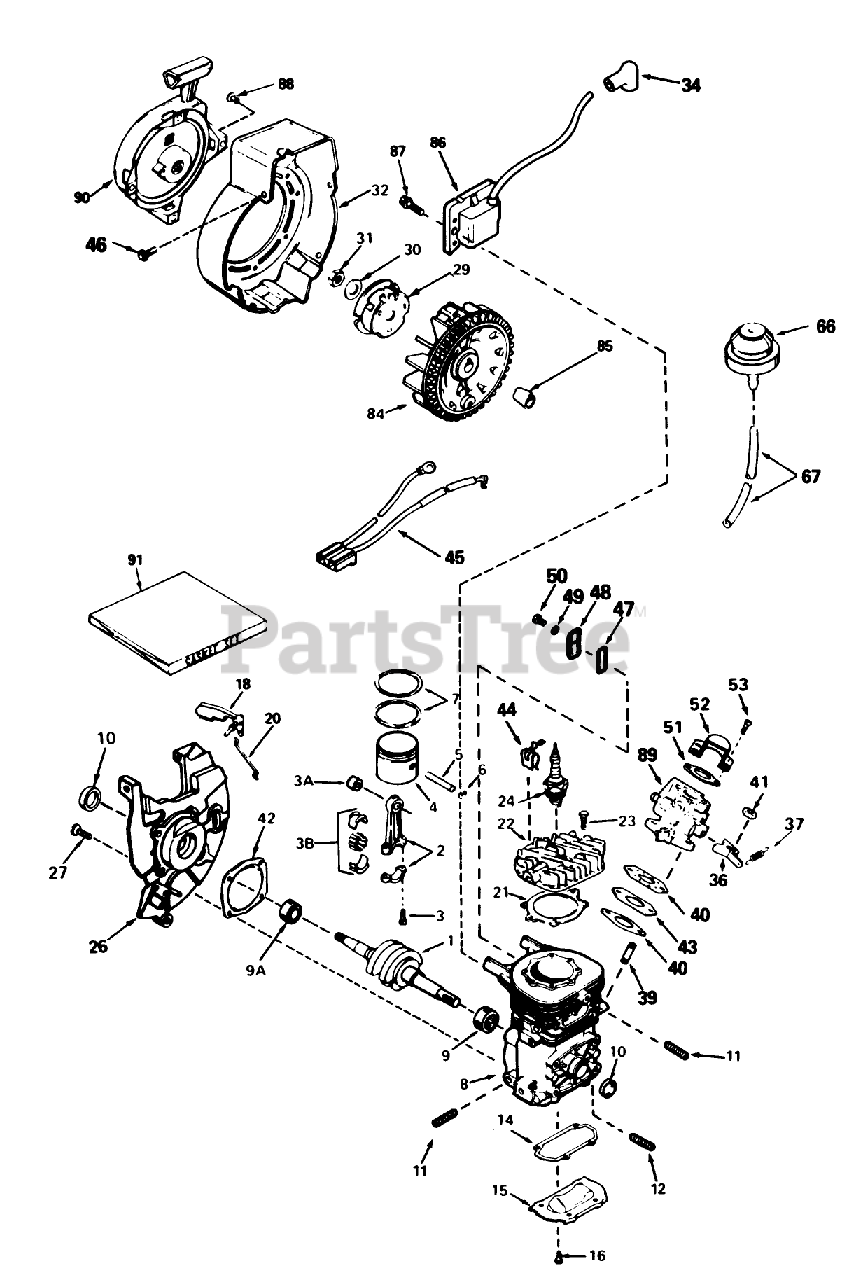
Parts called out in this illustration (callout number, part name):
1	Crankshaft
2	Rod Assy.-Connecting (Incl. Ref. #3, 3A 3B)
3	Bearing Liner Set-Needle (37 needles)
3A	Bolt-Rod, Connecting
3B	Bearing-Cartridge
4	Piston
5	Pin-Piston
6	Ring-Retaning
7	Ring Set
8	Block Assy.-Cylinder (Order short block if replacement is required.)
9	Bearing-Needle
9A	Bearing-Ball
10	Seal-Oil
14	Cover
15	Plate-Cover
16	Screw (T-25, 10-24 x 1/2)
18	Vane-Air
20	Link-Governor
21	Gasket, Head
22	Head-Cylinder
23	Screw (T-30, 1/4-20 x 3/4)
24	Spark Plug-Resistor (R C J 8Y)
26	Base Assy.-Blower Housing (Incl. Ref. #10)
27	Screw (T-30, 1/4-20 x 5/8)
29	Cup-Starter
30	Washer-Belleville
31	Nut-Flywheel
32	Housing-Blower
34	Cover-Spark Plug
36	Lever-Adjusting, Rpm
37	Spring-Governor
40	Gasket-Carburetor
41	Locknut
42	Gasket, Shroud Base
43	Spacer
44	Clip-Wire
45	Harness-Wire
46	Screw-Hex, Hd.
47	Gasket-Cover
48	Comp. Release Cover
49	Washer
50	Screw (T-25, 10-24 x 1/2)
51	Gasket
52	Baffle-Carburetor
53	Screw
66	Primer Assy.
67	Line-Primer
84	Flywheel
85	Blade (20 inch)
86	Solid State
87	Screw
88	Rivet-Pop (3/16" Dia.)(Can be purchased locally)
89	Carburetor (Incl. Ref. #40)
90	Starter-Rewind
91	Gasket Set
